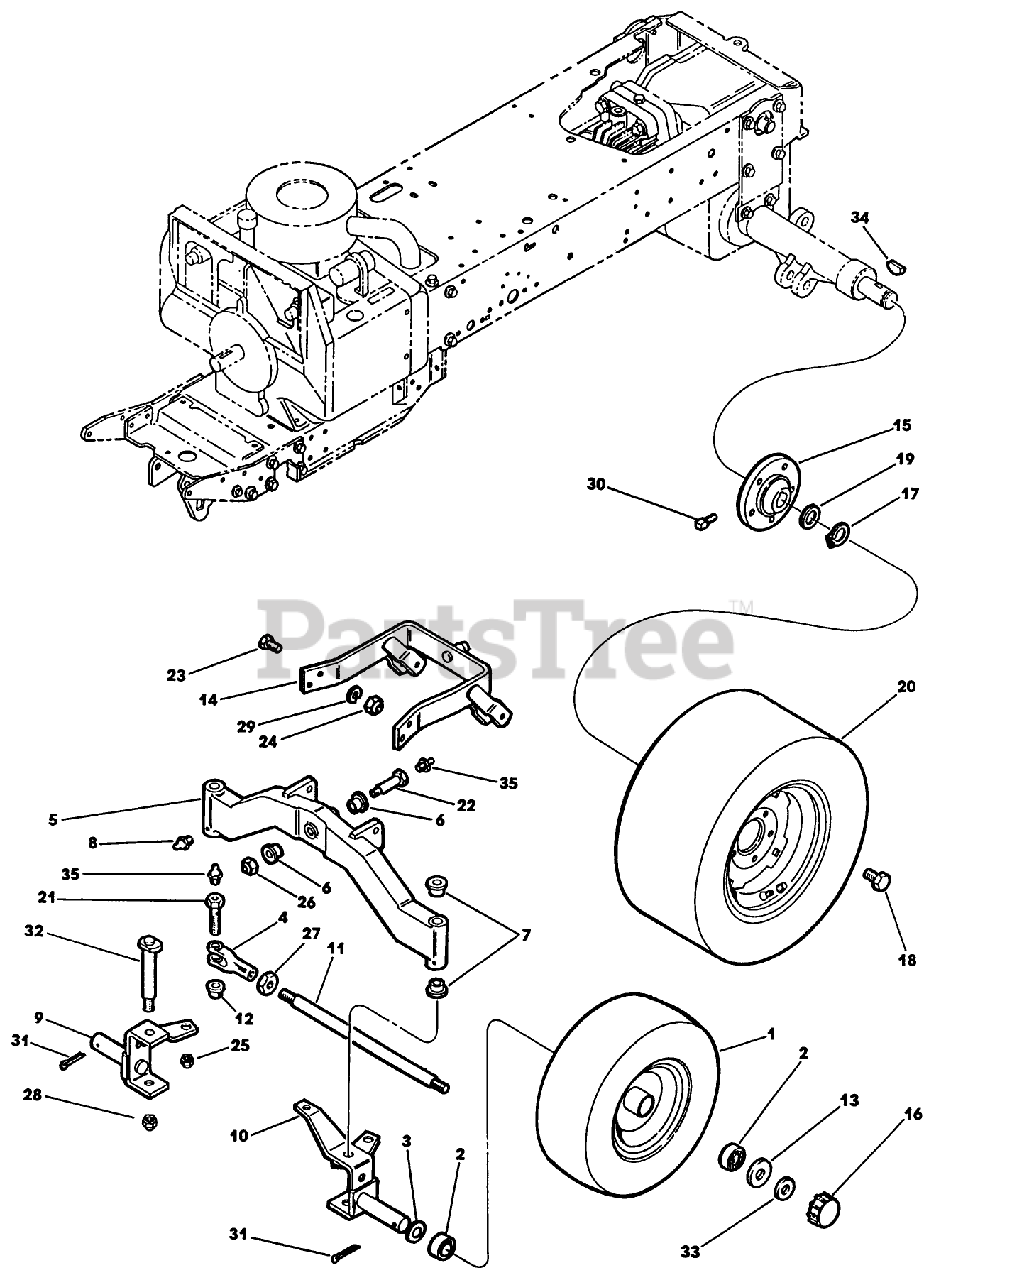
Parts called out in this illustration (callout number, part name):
4	CLEVIS
12	SPACER
13	WASHER
14	SUPPORT AY-AXLE PV *B
15	HUB - WHEEL S
24	NUT-LOCKING
25	NUT-HEX CONE LOK
26	NUT-HEX
29	WASHER
32	PIN AY-KING
34	KEY - WOODRUFF
